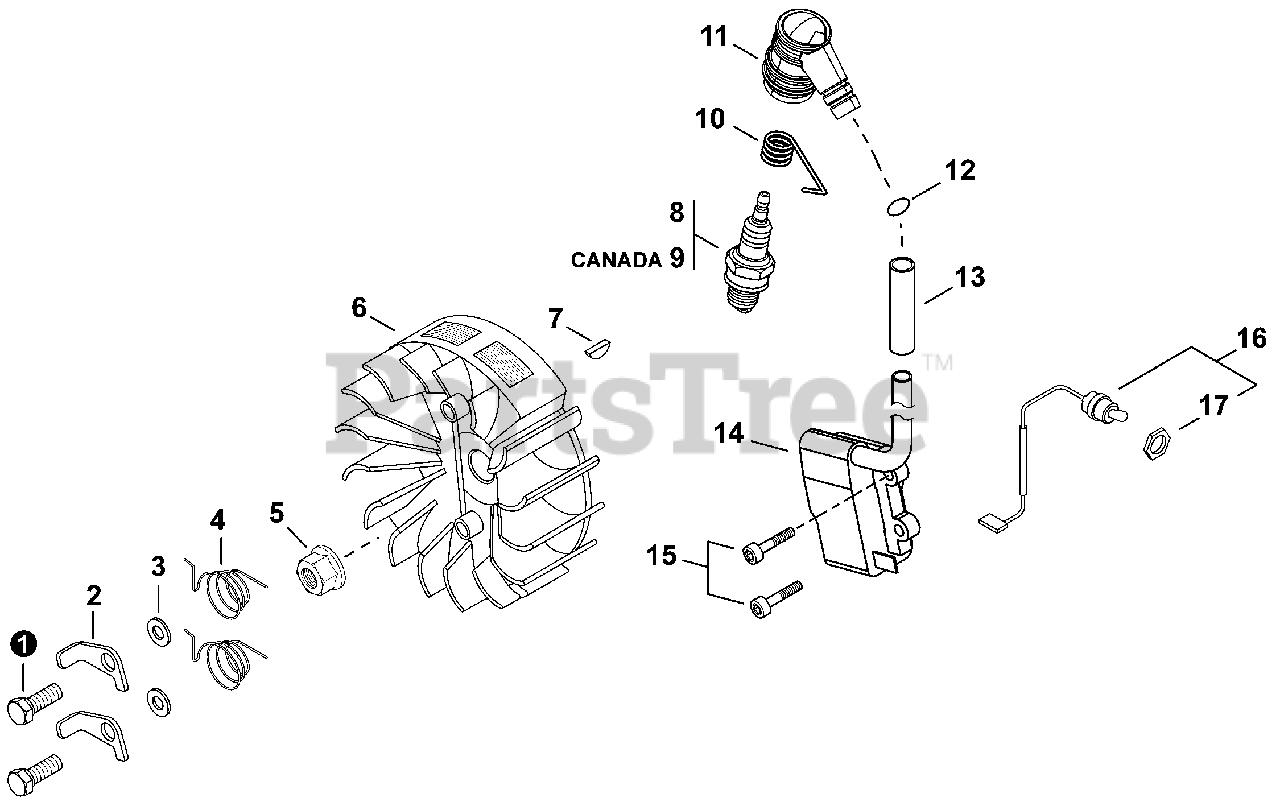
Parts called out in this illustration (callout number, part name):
3	WASHER 6
4	SPRING, TORSION
5	NUT M8×1.0
6	FLYWHEEL
7	KEY, WOODRUFF 3×10
8	SPARK PLUG - BPM8Y
9	SPARK PLUG - BPMR8Y
10	TERMINAL, SPARK PLUG
11	CAP, SPARK PLUG
12	O-RING 7
13	TUBE, INSULATOR
14	COIL, IGNITION
15	BOLT, ADHESIVE M4×20
16	SWITCH ASSY, ON-OFF
